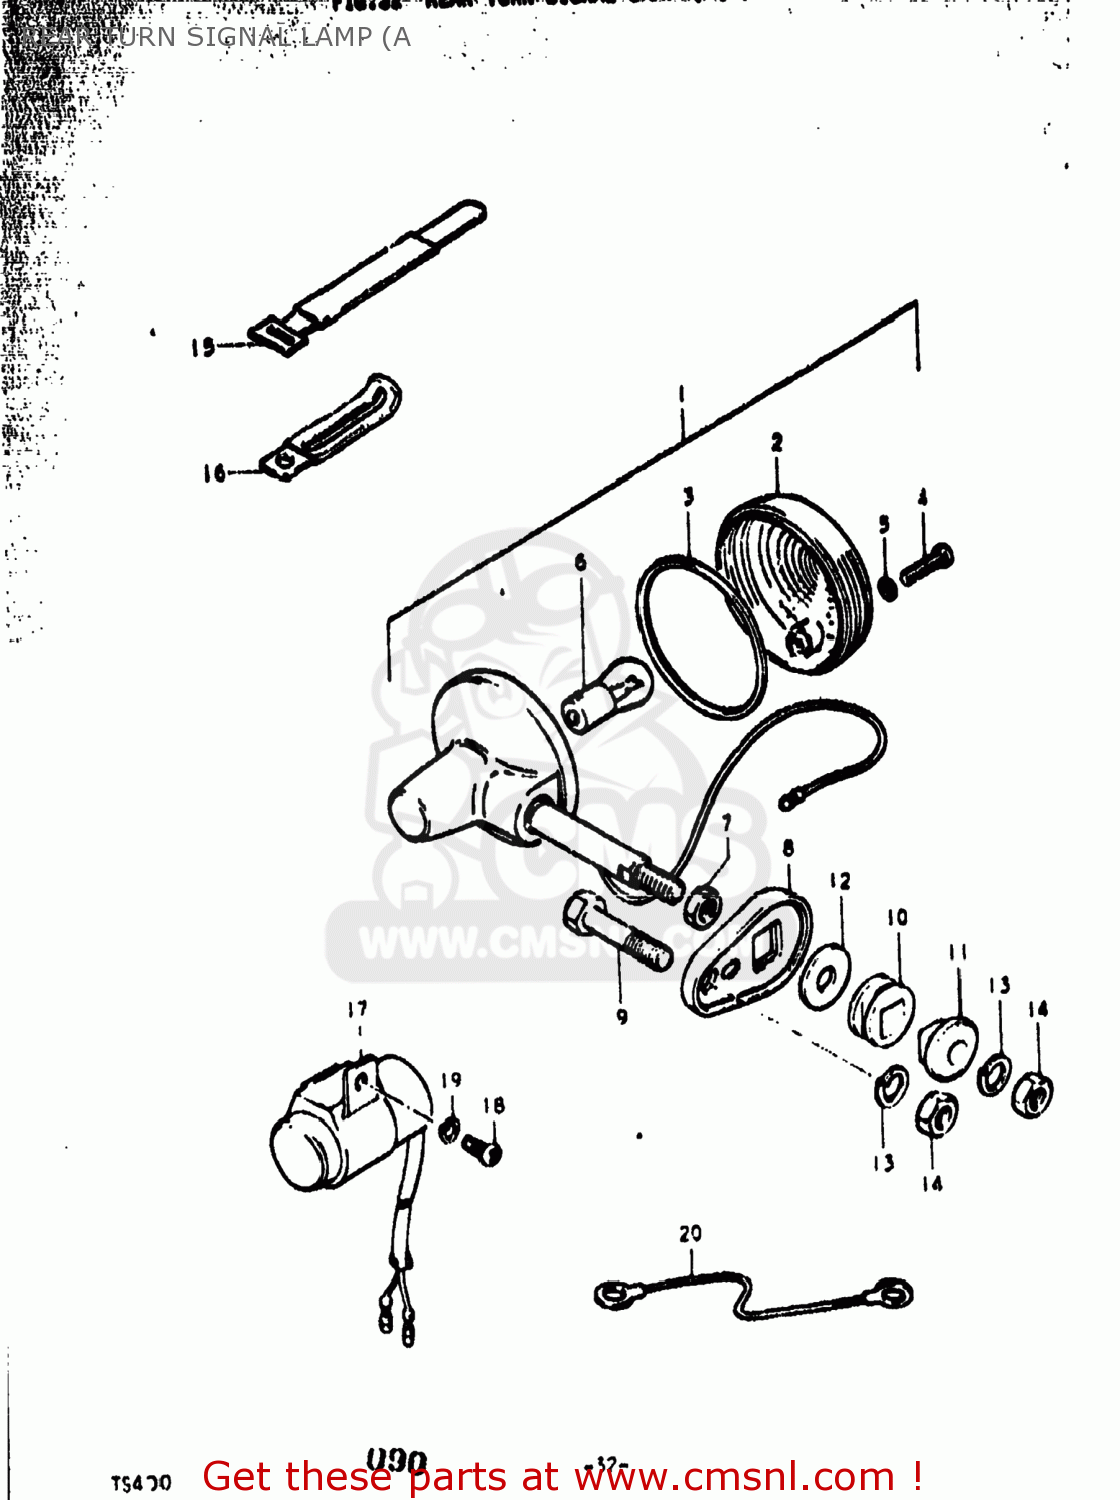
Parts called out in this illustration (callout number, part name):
1	LAMP ASSEMBLY,REAR TURN SIGNAL
2	LENS
3	GASKET (NAS)
4	SCREW
5	GASKET (NAS)
6	BULB(6V17W,STANLEY,A4513A)
7	NUT
8	BRACKET,TURN SIGNAL
9	BOLT 10X55
10	CUSHION
11	SPACER,RR TURNSIGNAL LAMP
12	WASHER (10.5X30X2.3)
13	LOCK WASHER
14	NUT
15	CLAMP
16	CLAMP L:35
17	RELAY,TURN SIGNAL
18	SCREW
19	LOCK WASHER
20	WIRE
